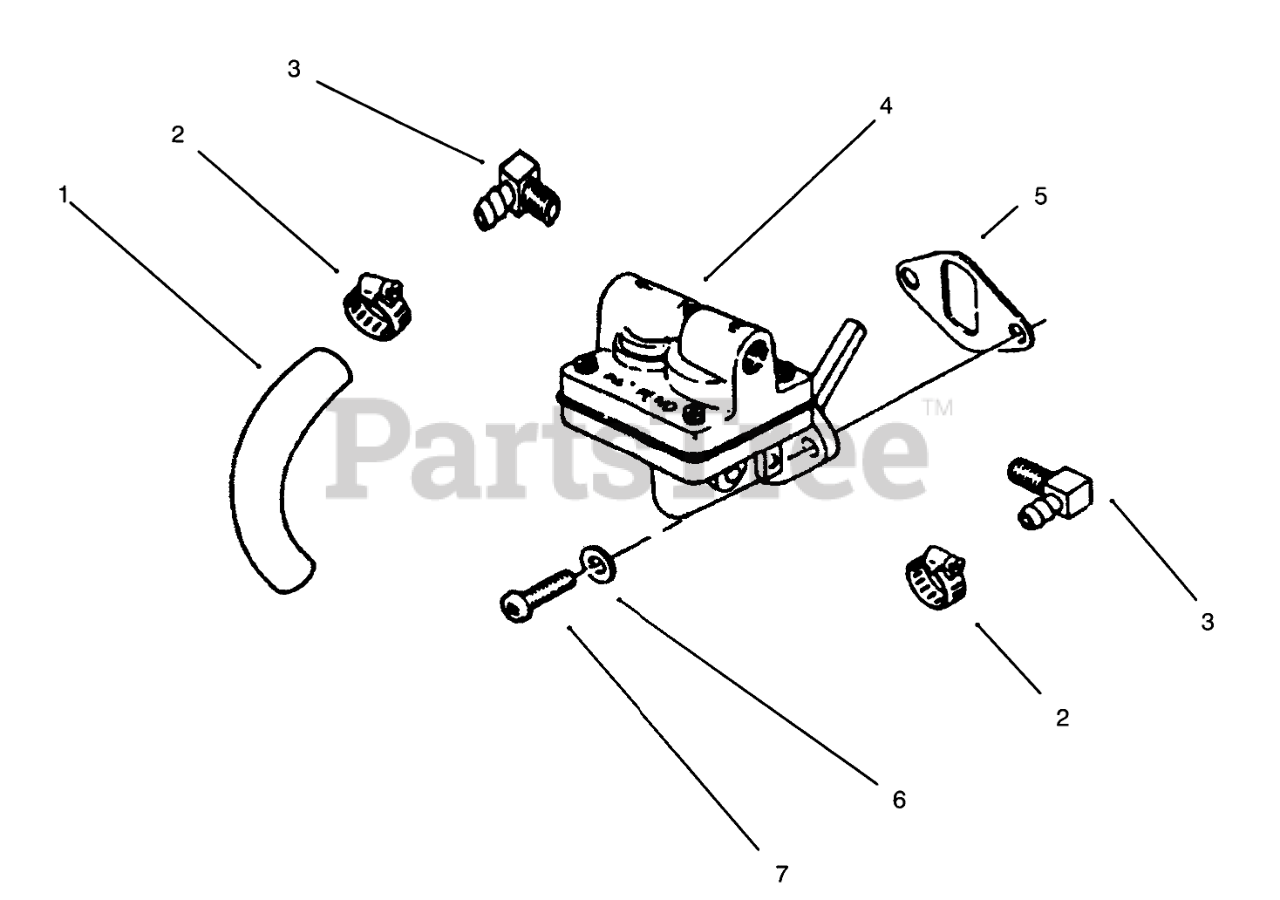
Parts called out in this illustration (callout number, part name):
1	Line-Fuel
2	Clamp
3	Connector 90
4	Pump Assy-Fuel (Incl. Ref.#5 & 7)
5	Gasket
6	Washer
7	Screw-Pozidrive
